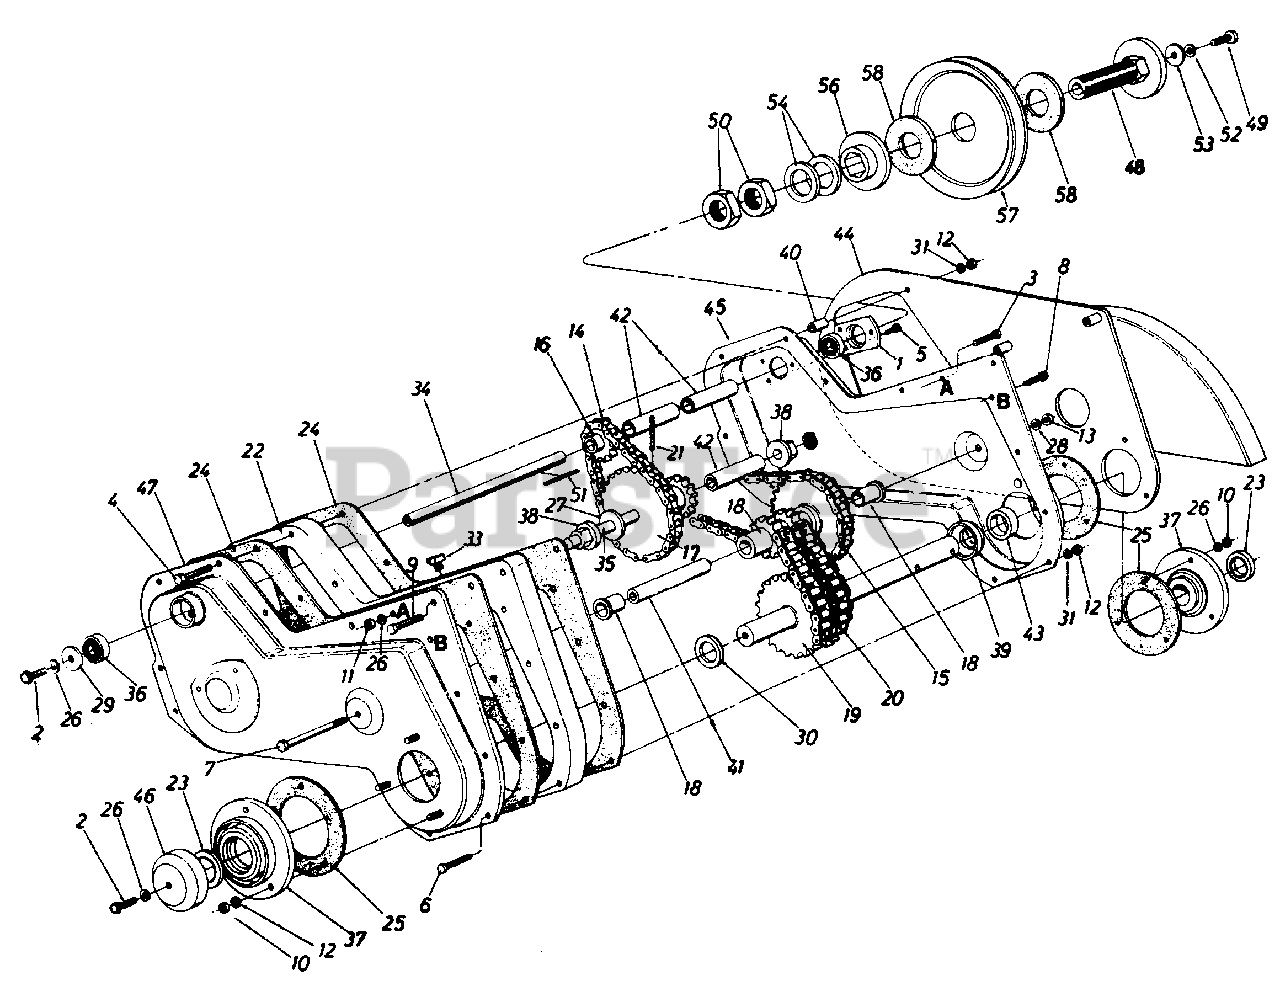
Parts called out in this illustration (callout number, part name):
1	Bearing Housing 1-3/8" Dia.
2	Hex Bolt 5/16-18 x .88" 4. Spec.
3	Hex Bolt 5/16-18 x 1.50" Lg.*
4	Hex Bolt 1/4-20 x 2.75" Lg.*
5	Hex Wash. S- Tap. Scr. 1/4-20 x .50" Lg.
6	Hex Bolt 1/4-20 x 1.50" Lg.*
7	Hex Bolt 3/8-16 x 4.5" Lg.
8	Hex Wash. Hd. Bolt 1/4-20 x 1.5" Lg.
9	Hex Wash. TT -Tap Scr. 5/16-18 x 1.75" Lg.
10	Hex Cent. L.-Nut 5/16-18 Thd.
11	Hex Nut 5/16-18 Thd.*
12	Hex Nut 1/4-20 Thd.*
13	Hex Nut 3/8-16 Thd.*
14	#41 Chain 1/2" Pitch x 34 Links - Endless
15	#42 Chain 1/2" Pitch x 48 Links - Endless
16	Sprocket 10 Tooth .500" Pitch
17	10 & 28 Teeth Sprocket Ass'y.
18	8-2 & 28 Sprocket Sleeve Ass'y.
19	18-2 Sprocket Shaft Ass'y.
20	#50-2 Chain 5/8" Pitch x 28 Links- Endless
21	Spring Pin Spir. 1/4" Dia. x 1.50" Lg.
22	Spacer Block - Tiller Housing
23	Oil Seal Double Lip-1-1/4" Dia.
24	Gasket for Tiller Housing
25	Gasket for Brg.-Housing
26	L.-Wash. 5/16" I.D.*
27	Fl.-Wash. .640" I.D. x 1.24" O.D.
28	L.-Wash. 3/8" I.D. Heavy Duty
29	Fl.-Wash. .344" I.D. x 1.125" O.D.
30	Special Washer
31	L.-Wash. 1/4" I.D.*
33	Vent Plug
34	Jack Shaft .525" I.D. x 7.78" Lg.
35	Sprocket Shaft .63" Dia. x 5.0" Lg.
36	Ball Brg. .62" I.D. x 1.38" O.D.
37	Bearing Housing- 1-1/4"
38	Hex Flange Brg.
39	Spacer 1.25" I.D. x 2.0" O.D.
40	Spacer.28" I.D. x .62" O.D. x .90" Lg.
41	Spacer.38" I.D. x .62" O.D. x 3.44" Lg.
42	Spacer .62" I.D. x .88" O.D. x 1.56" Lg.
43	Spacer 1.25" I.D. x 1.62" O.D. x .50" Lg.
46	Dust Cap .320" Dia. Hole
49	Hex Bolt 5/16-18 x 1.25" Lg. Grade 5
50	Hex Jam Nut 1.0-14 x 28 Thd.
51	Sq. Key 3/16 x 1.50" Lg.
52	L.-Wash. 5/16" I.D.*
53	Fl.-Wash. .344" I.D. x 1.125" O.D.
54	Spring Bell Wash. 1.0" I.D. x 2.0" O.D.
56	Floating Disc 3-1/4" O.D. x 1.0" I.D.
57	5/8 V-Pulley 1.50" I.D. x 6.50"
58	Friction Pad 3-1/4" O.D. x 1-3/8" I.D.
